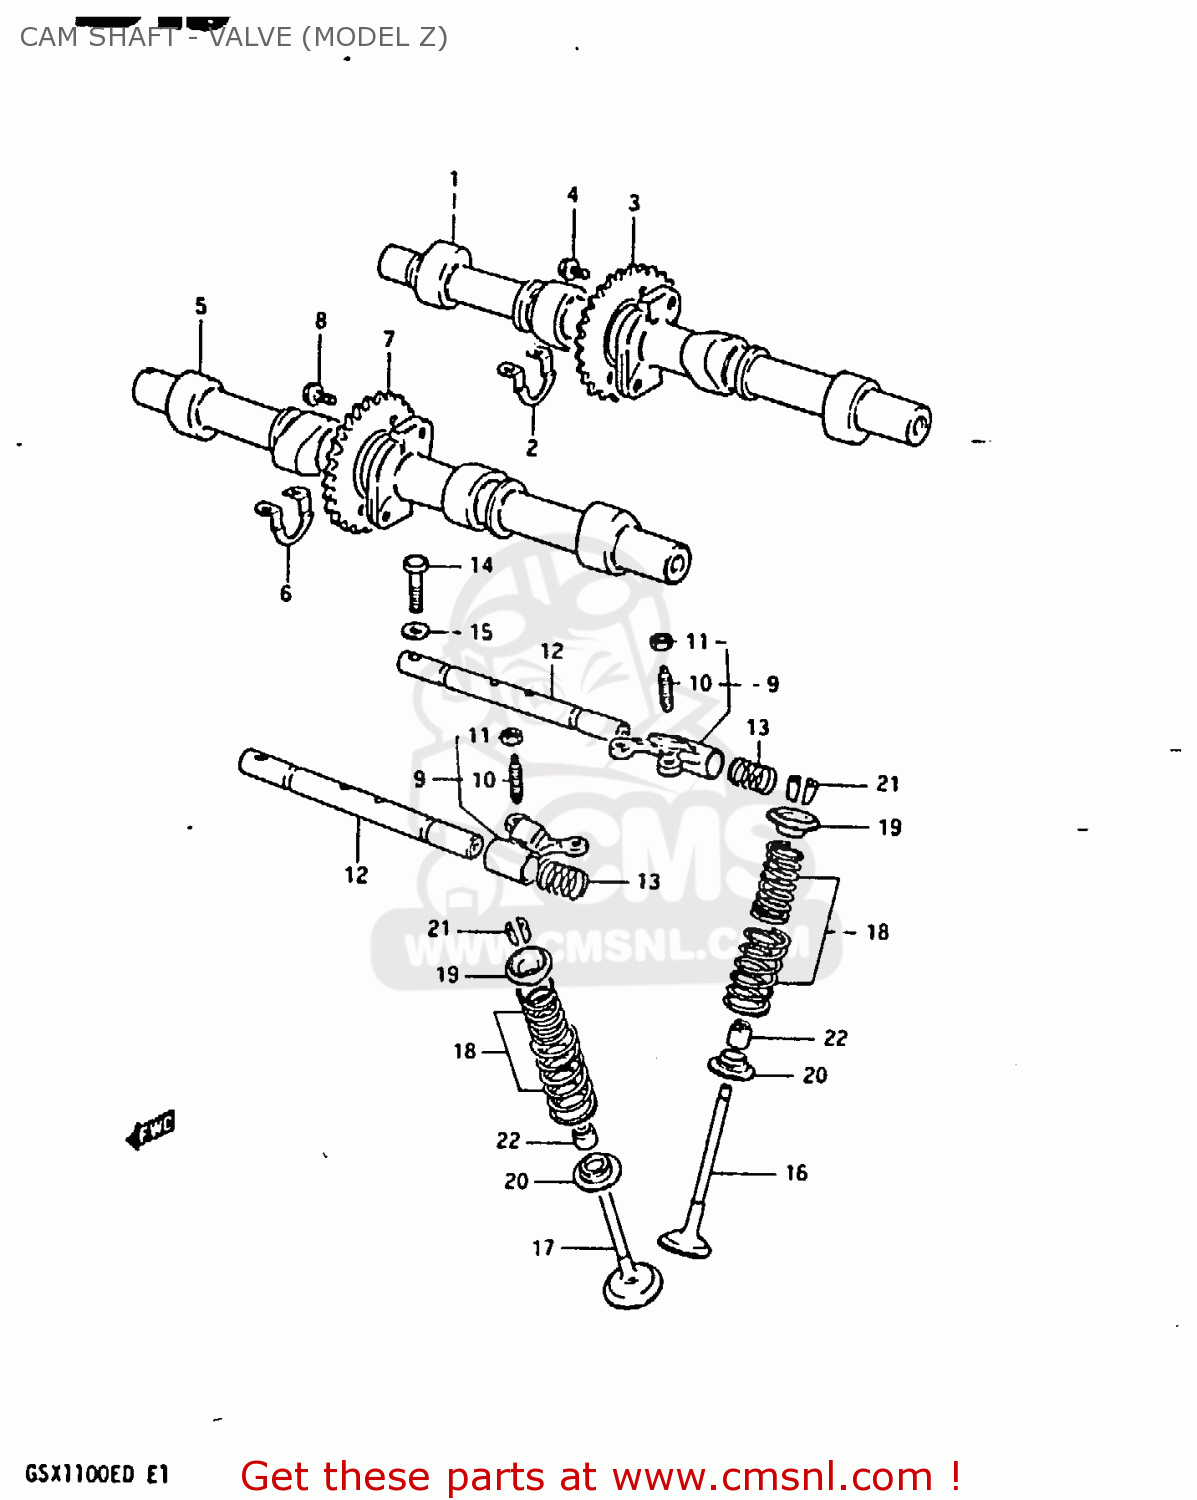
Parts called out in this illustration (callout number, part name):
1	CAMSHAFT,INTAKE
2	SHIM,CAMSHAFT
3	SPROCKET,INTAKE CAMSHAFT
4	BOLT(7X11)
5	CAMSHAFT SET,EXHAUST
6	SHIM,CAMSHAFT
7	SPROCKET,EXHAUST CAMSHAFT
8	BOLT(7X11)
9	ARM,VALVE ROCKER
10	SCREW,TAPPET ADJUSTING
11	NUT,ADJUSTING
12	SHAFT,VALVE ROCKER
13	SPRING
14	BOLT
15	WASHER
16	VALVE,INTAKE
17	VALVE,EXHAUST
18	SPRING SET,VALVE
19	RETAINER,VALVE SPRING
20	SEAT,VALVE SPRING
21	COTTER VALVE
22	OIL SEAL
